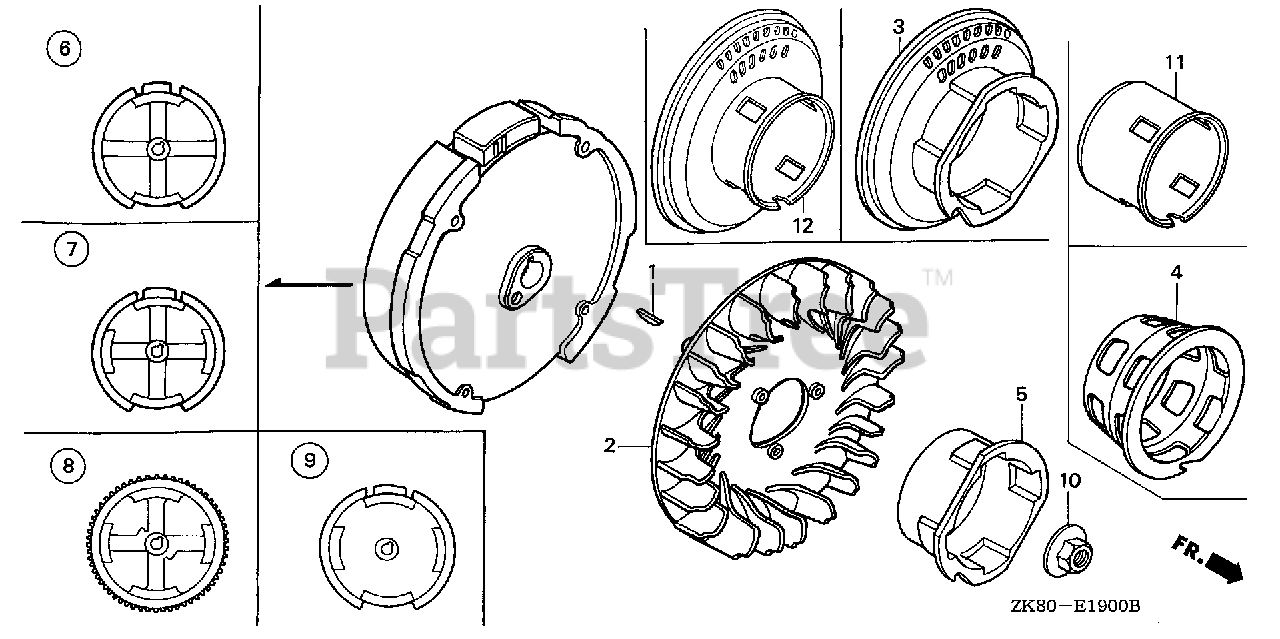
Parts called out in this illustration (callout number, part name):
1	KEY, SPECIAL WOODRUFF (25X18)
2	FAN, COOLING
5	PULLEY, STARTER
10	NUT, SPECIAL (14MM)
11	PULLEY, STARTER
